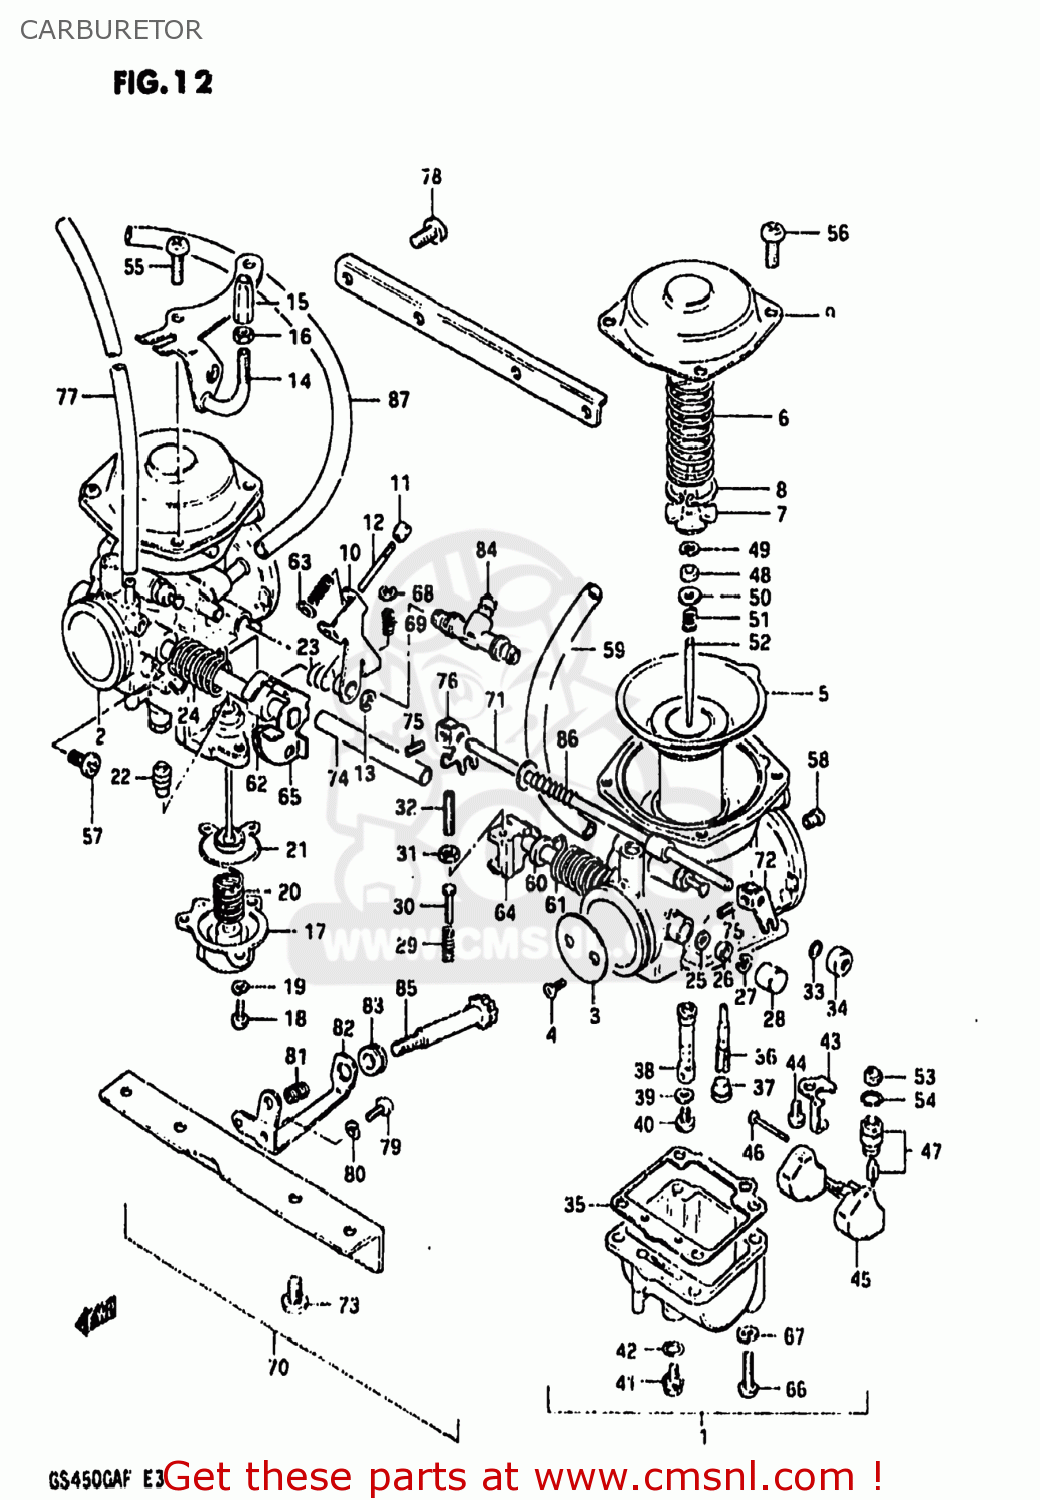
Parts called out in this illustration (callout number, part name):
1	CARBURETOR ASSEMBLY,LEFT (BS
2	CARBURETOR ASSEMBLY
3	VALVE,THROTTLE
4	SCREW
5	DIAPHRAGM ASSEMBLY
6	SPRING
7	HOLDER,GUIDE
8	E RING
9	COVER
10	LEVER,ACCELERTION PUMP
11	O-RING
13	E RING,ACCELETION LEVER
14	BRACKET
15	ADJUSTER
16	NUT
17	COVER ASSEMBLY,DIAPHRAGM
18	SCREWM4X0.7X10
19	LOCK WASHER
20	SPRING,ACCELERATOR PUMP
21	DIAPHRAGM ASSY,ACCELERATING
22	BOOT, ACCELE PUMP ROD
23	SPRING
24	SPRING
25	SEAL
26	GASKET,THROTTLE SHAFT (NAS)
27	E RING
28	CAP
29	SPRING,THROTTLE SCREW
30	PIN,THROTTLE LEVER
31	NUT
32	SCREW
33	O RING
34	CAP,STARTER VALVE
35	GASKET,FLOAT CHAMBER
36	JET,PILOT(42.5)
37	PLUG,NEEDLE JET
38	JET,NEEDLE
39	WASHER,NEEDLE NOZZLE
40	JET,MAIN(120)
41	PLUG,DRAIN
42	GASKET (NAS)
43	PLATE,NEEDLE VALVE FITING
44	SCREW
45	FLOAT
46	PIN,FLOAT
47	VALVE ASSY,NEEDLE
48	RING
49	CLIP
50	WASHER,JET NEEDLE
51	SPRING
52	NEEDLE JET
53	FILTER
54	O-RING,NEEDLE VALVE
55	SCREW 5X10
56	SCREW
57	SCREW
58	JET,AIR(135)
59	HOSE
60	SPACER,THROTTLE SHAFT
61	SPRING
62	SPACER,THROTTLE SHAFT
63	GUIDE,HOLDER
64	SHAFT ASSEMBLY
65	SHAFT ASSEMBLY
66	SCREW
67	LOCK WASHER
68	E-RING
69	SPRING,THROTTLE SCREW
70	CARBURETOR ASSEMBLY
71	SHAFT,STARTER
72	LEVER
73	SCREW
74	HOSE
75	SCREW
76	LEVER,STARTER
77	HOSE 4.5X8X390
78	SCREW 5X12
79	SCREW
80	LOCK WASHER
81	SPRING,THROTTLE ADJUST
82	BRACKET,THROTTLE ADJUST
83	CAP,RUBBER
84	NIPPLE,CARBURETOR
85	SCREW
86	SPRING,STARTER
87	HOSE
